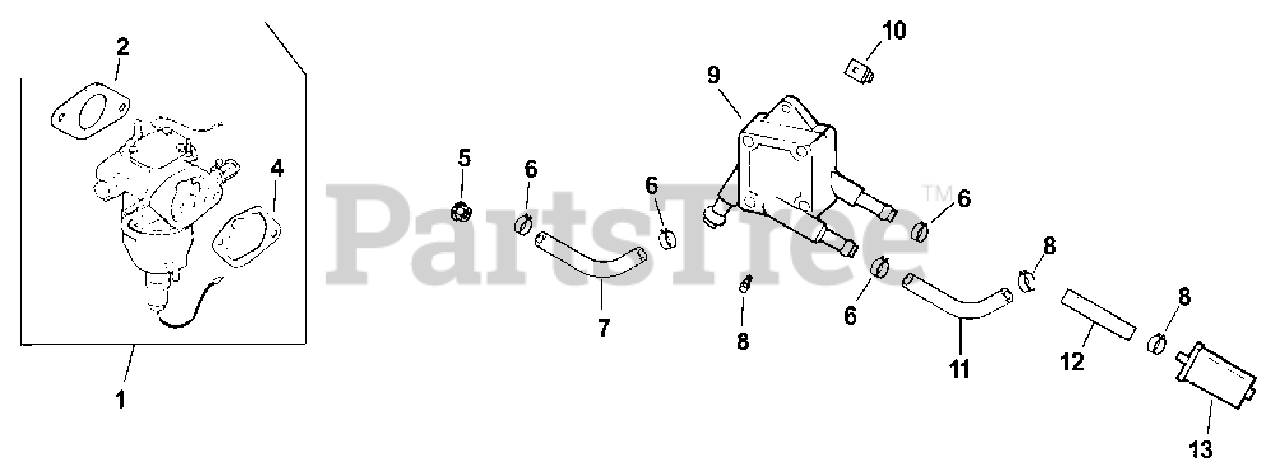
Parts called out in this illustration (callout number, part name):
1	Carburetor w/Gaskets
2	Carburetor Gasket
4	Air Cleaner Base Gasket
5	Hex Flange Nut (M6 x 1.0)
6	Hose Clamp
7	Fuel Line (12-1/2")
8	Hex Cap Screw (M6 x 1.7 x 18)
10	Plastic Nut
11	Fuel Line (10-1/2")
12	Fuel Line (3-1/2")
13	Fuel Filter
